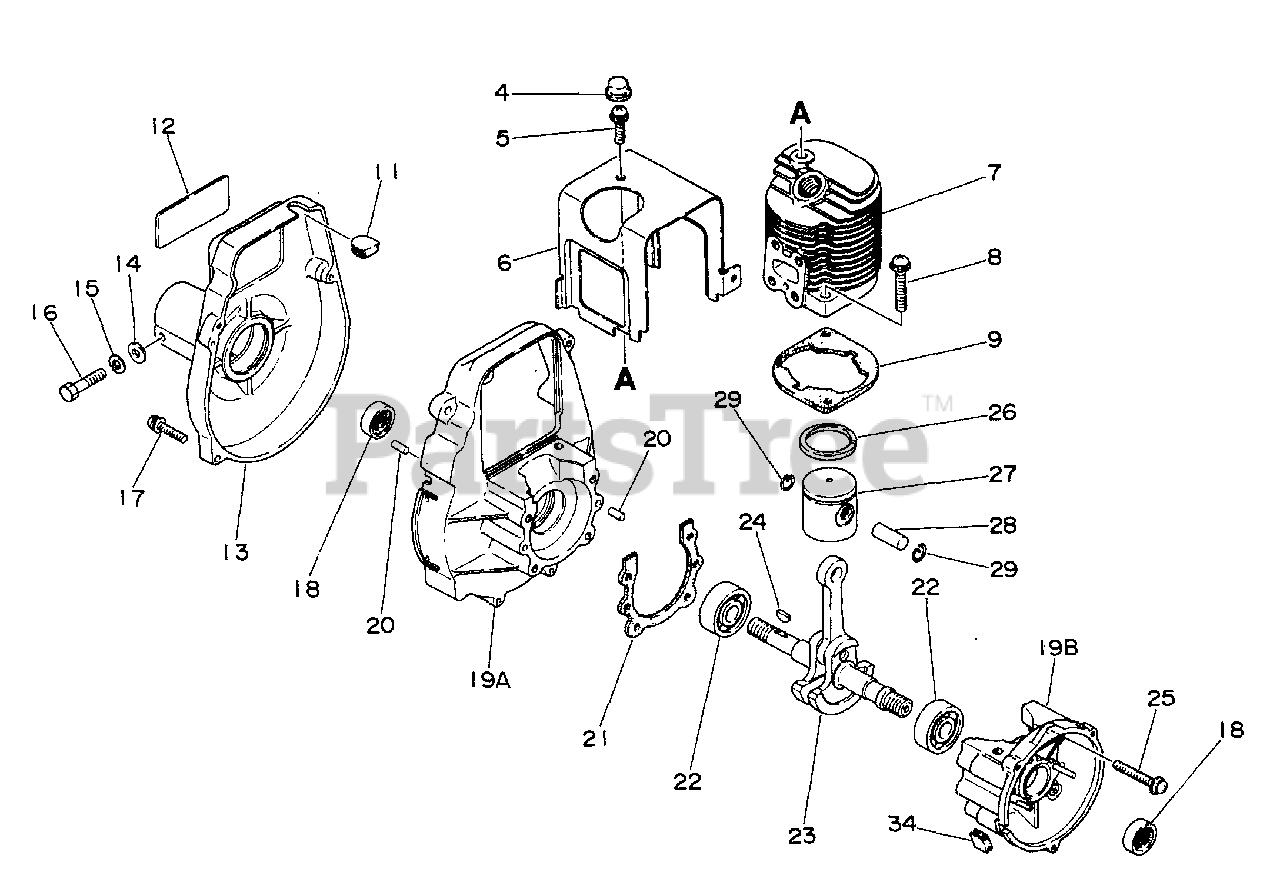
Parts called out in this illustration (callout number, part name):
5	SCREW - 5X10
6	COVER, ENGINE
7	CYLINDER
8	SCREW - 6X20
9	GASKET, CYLINDER
11	PLUG
12	LABEL - MODEL
13	CASE, FAN
14	WASHER - 5
15	LOCKWASHER - 5
16	BOLT - 5X20
17	SCREW - 4X20
18	SEAL, OIL
19	CRANKCASE KIT
19A	CRANKCASE KIT
19B	CRANKCASE KIT
20	PIN - LOCATING
21	GASKET, CRANKCASE
22	BEARING, BALL - 6200
23	CRANKSHAFT ASSY
25	SCREW - 5X30
26	RING, PISTON
27	PISTON
28	PIN, PISTON
29	RING, RETAINING
34	PLUG
